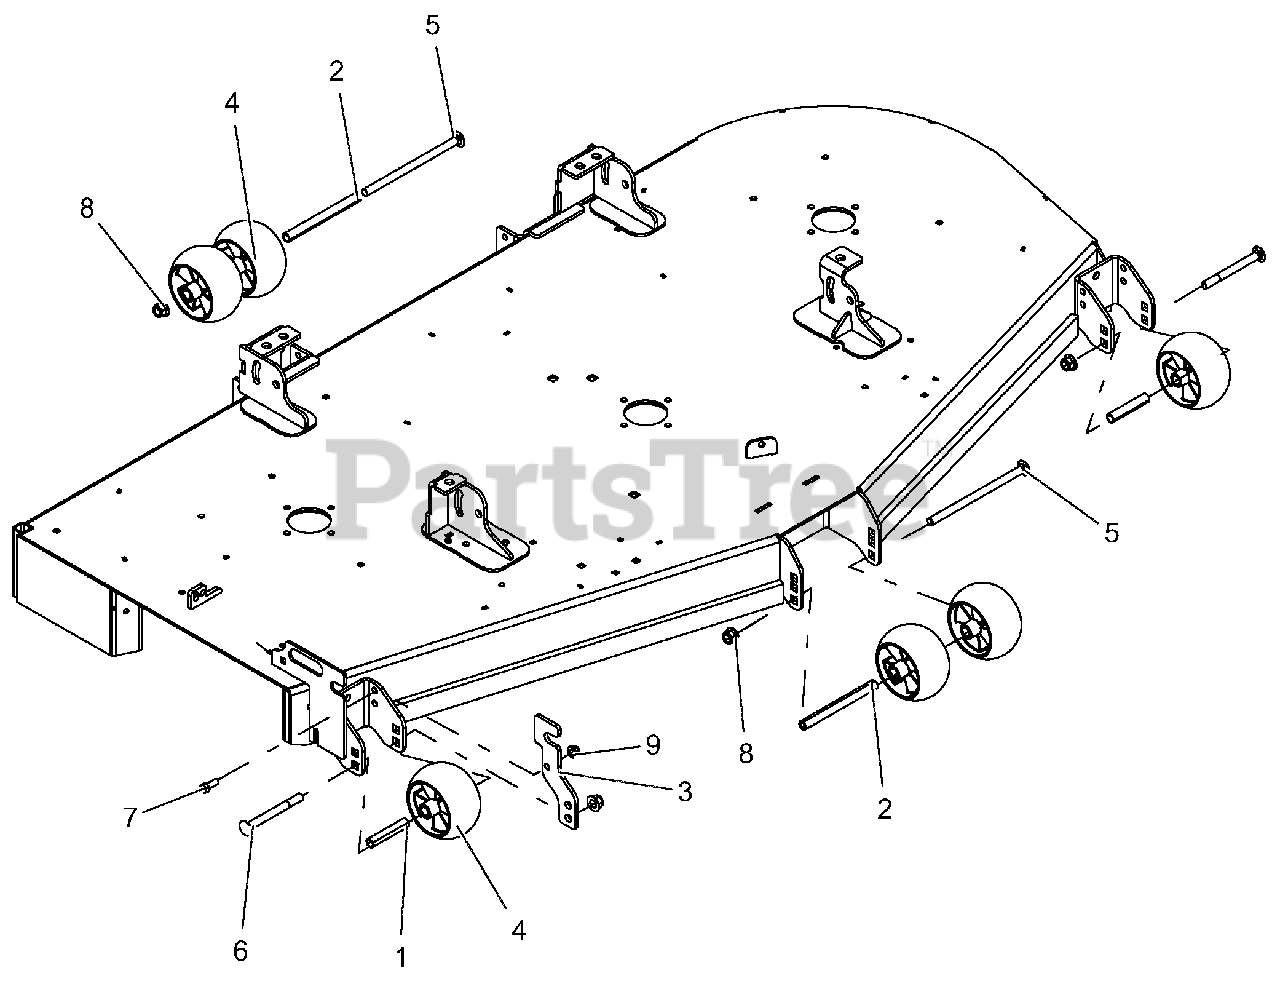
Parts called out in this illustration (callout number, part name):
1	SPACER, .510X.625X3.35
2	SPACER, .510X.625X6.70
3	CHUTE STORAGE BRACKET-RED
4	ANTI-SCALP WHEEL - 5X3 CTR
5	@BLT-RDHDSQNK .50-13X8.50 Y
6	BLT-RDHDSQNK .50-13X5.00 G5
7	BLT-HEX .38-16X1.00 GR5 YWZC
8	NUT-LK-NYL-FLG .50-13 YWZC
9	NUT-LK-NYL-FLG .38-16 YWZC
